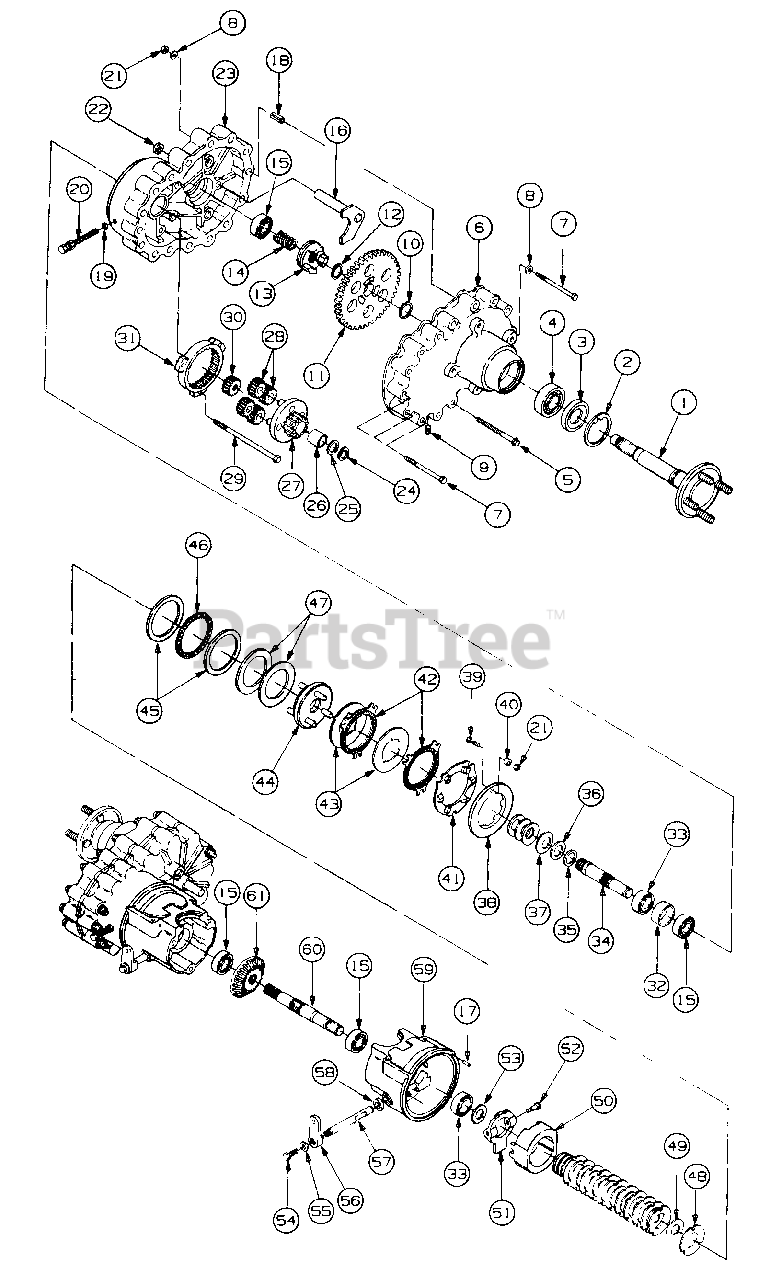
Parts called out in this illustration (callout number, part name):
1	Axle Assy
2	Ring, Inverted Retainer
3	Seal, Oil
4	Bearing
5	Screw, Hex Wash Hd Tapp, 1/4-20 X 2.31 Lg
6	Housing RH Outer Reduction
7	Screw, Hex Cap, 1/4-20 X 4.0 Lg
8	Washer, Flat, .25 X .62
9	Plug, Magnetic, 1/2-14 NPTF
10	Ring, External Retainer
11	Gear, Axle Bull
12	Ring, Retainer, 7/8 Shaft
13	Collar, Drive
14	Spring, Compression, 1.095 OD X 1.75 Lg
15	Bearing
16	Shaft Assy, Neutral
17	Pin, Dowel, 3/16 Dia X .87 Lg
18	Pin, Slotted Spring, 7/16 X 1.0 Lg
19	O-Ring, .239 ID X .064 Thk
20	Bolt, Brake Adiuster (Includes Ref No. 19)
21	Nut, Hex Top Lock, 1/4-20 GR5
22	Seal, Oil
23	Housing, RH Inner Reduction
24	Ring, Retainer
25	Washer, Flat, .696 X 1.12 X .030 Thk
26	Bearing, Sleeve
27	Carrier Assy (Includes Ref No. 26)
28	Gear, Planet
29	Bolt Hex Patch Lock, 3/8-16 X 8.5 Lg GR5
30	Gear, Sun
31	Gear, Ring
32	Spacer, Bearing
33	Bearing, Angular Contact
34	Shaft, Output
35	Washer, Flat, .915 X 1.37 X .010 Thk
36	Washer Flat, .88 X 1.50 X .030 Thk
37	Washer, Spring, .882 X 1.77 X .049 Thk
38	Ramp, RH Brake
39	Screw, Hex Cap, 1/4-20 X .88 Lg
40	Spacer, .254 ID X .500D X .390 Lg
41	Plate RH Brake Adjustment
42	Disc, Friction
43	Disc, Brake
44	Hub Assy, Drive
45	Washer, Thrust, 3.0 X 3.75 X .125 Thk
46	Bearing, Thrust, 3.0 X 3.75 X .078 Thk
47	Washer Flat, 2.765 X 3.75 X .020 Thk
48	Disk, Friction
49	Plate, Clutch
50	Hub, Brake
51	Arm, Brake Actuator
52	Bolt, Shoulder
53	Washer, Flat, .760 X 1.50 X .036 Thk
54	Screw, Hex Cap, 1/4-20 X .62 Lg GR5
55	Washer, Belleville, .265 X .75 X .062 Thk
56	Arm, Clutch/Brake
57	Shaft, Clutch/Brake Actuator
58	Seal, Oil
59	Housing, RH Clutch/Brake
60	Shaft, Drive
61	Gear, Bevel, 32T
